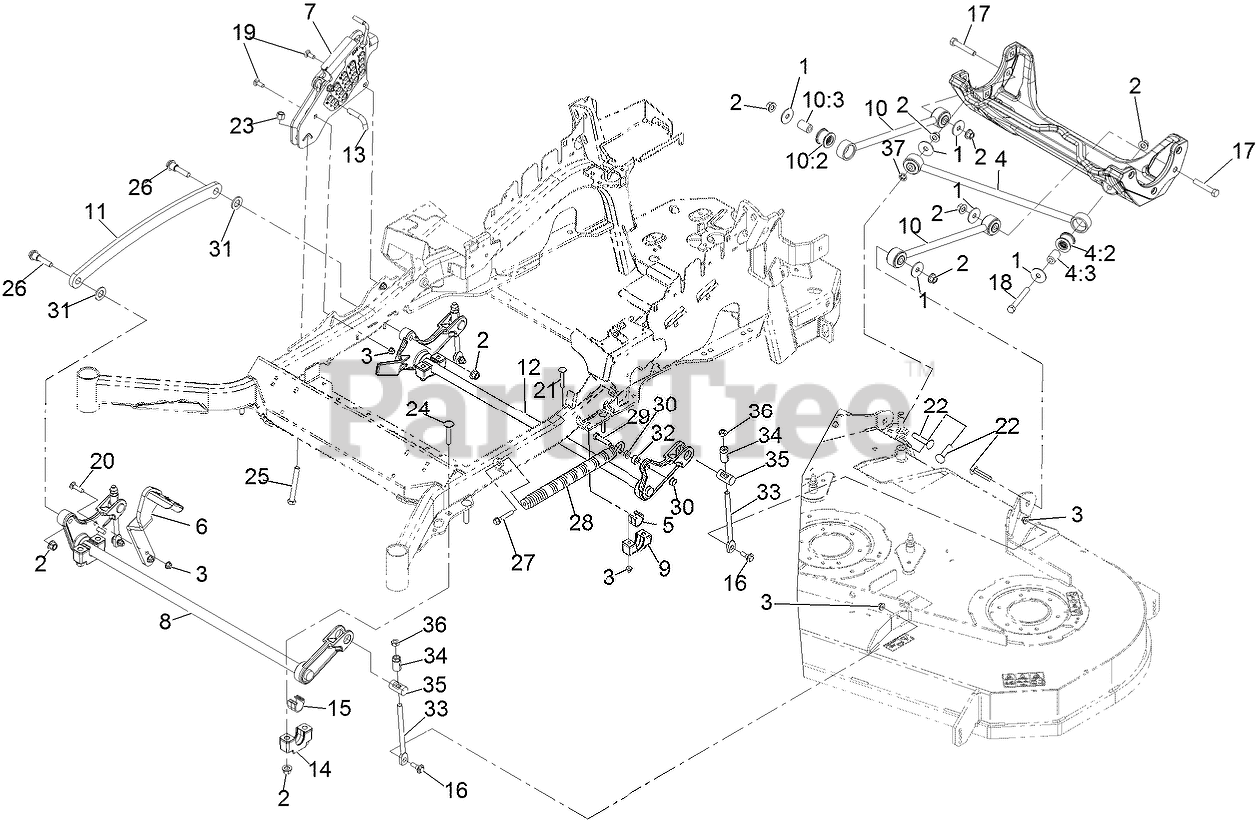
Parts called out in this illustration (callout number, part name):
1	WASHER-THRUST
2	Nut-Lock 1/2-13
3	NUT-HF, NI
4	PANHARD ROD ASM
4:2	BUSHING-SUSPENSION, RUBBER
5	BEARING-CROSS SHAFT, REAR
6	LEVER-FOOT
7	HOC ASM
8	DECKLIFT-FRONT
9	SUPPORT-CROSS SHAFT, BEARING REAR
10	DECK STRUT ASM
10:2	BUSHING-SUSPENSION, RUBBER
11	LINK-LIFT, DECK
12	LIFT-DECK, REAR
13	PIN-HOC
14	SUPPORT-CROSS SHAFT, BEARING
15	BEARING-CROSS SHAFT, FRON
16	SCREW-SHOULDER, HHF
17	SCREW-HH
18	SCREW-HH
19	BOLT-CARR
20	SCREW-CARR
21	Bolt-Carriage 3/8-16 X 2 1/4
22	SCREW-CARR
23	NUT-LOCK, NI
24	Bolt-Carriage 1/2-13 X 2 1/2 Spl Neck
25	BOLT-TAP
26	SCREW-HHF, SHOULDER
27	BOLT-SHOULDER
28	SPRING-EXTENSION
29	SCREW-HH
31	WASHER-FLAT
33	LINK-ADJUSTER, DECK LIFT
34	ADJUSTER-LIFT, DECK
35	TRUNNION
36	NUT-JAM
37	NUT-PUSH
